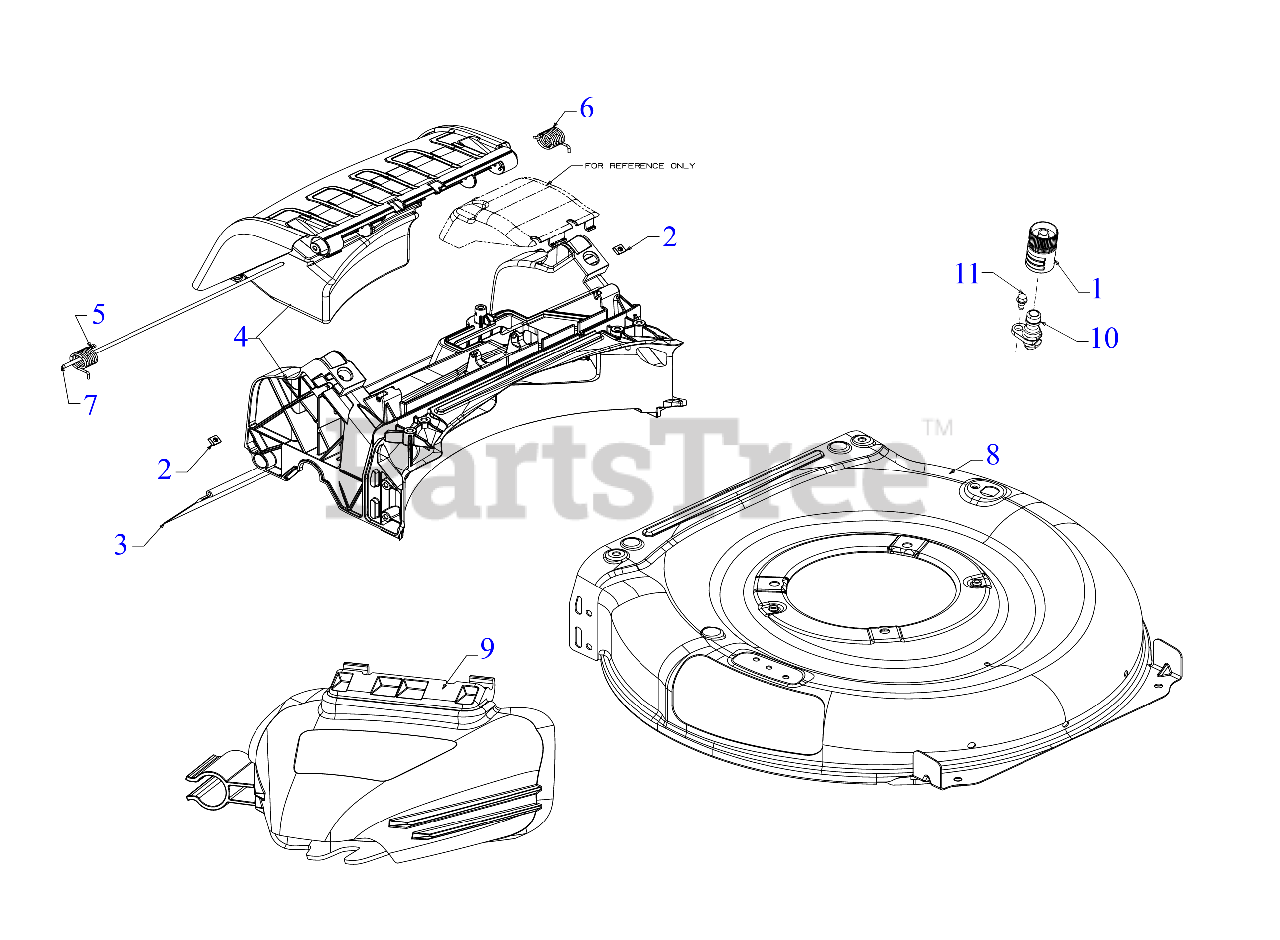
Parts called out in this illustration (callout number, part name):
1	WATER NOZZLE ADAPTER
2	SQUARE LOCK NUT 1/4X20
3	TRAILSHIELD
4	REAR BAFFLE ASSEMBLY
5	TORSION SPRING (RH)
6	TORSION SPRING (LH)
7	REAR DOOR PIVOT ROD
9	MOWER BLOWER CHUTE
10	DECK WASH NOZZLE
11	SHOULDER SCREW 1/4-20 x .50
